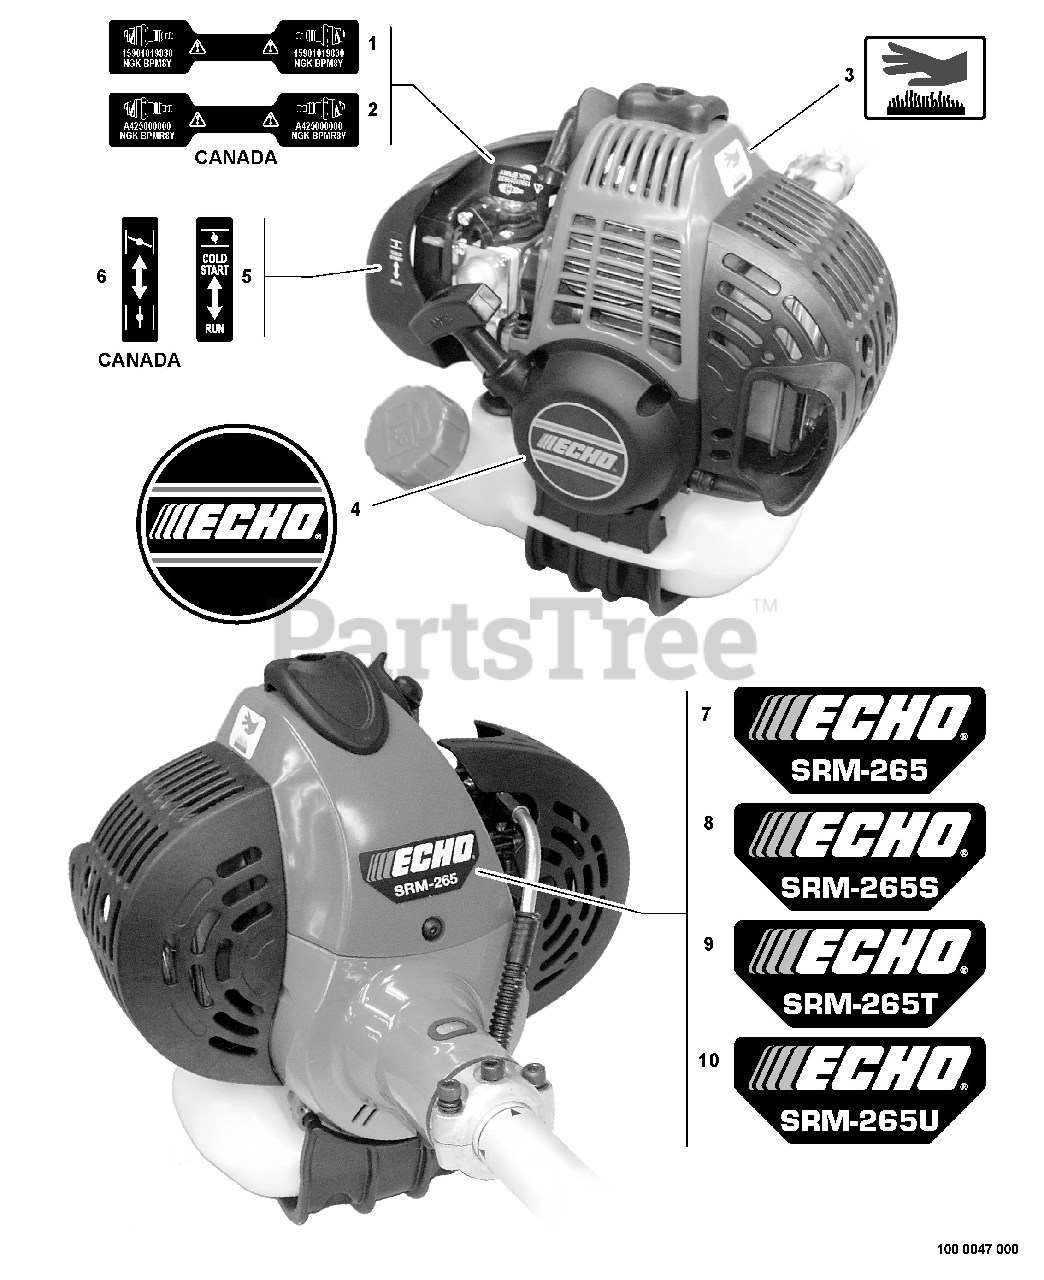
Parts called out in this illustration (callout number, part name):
1	LABEL - SPARK PLUG -- BPM-8Y
2	LABEL - SPARK PLUG -- BPMR-8Y
3	LABEL - HOT SURFACE
4	LABEL - ECHO
5	LABEL - CHOKE
6	LABEL - CHOKE
7	LABEL - MODEL SRM-265
8	LABEL - MODEL SRM-265S
9	LABEL - MODEL SRM-265T
10	LABEL - MODEL SRM-265U
